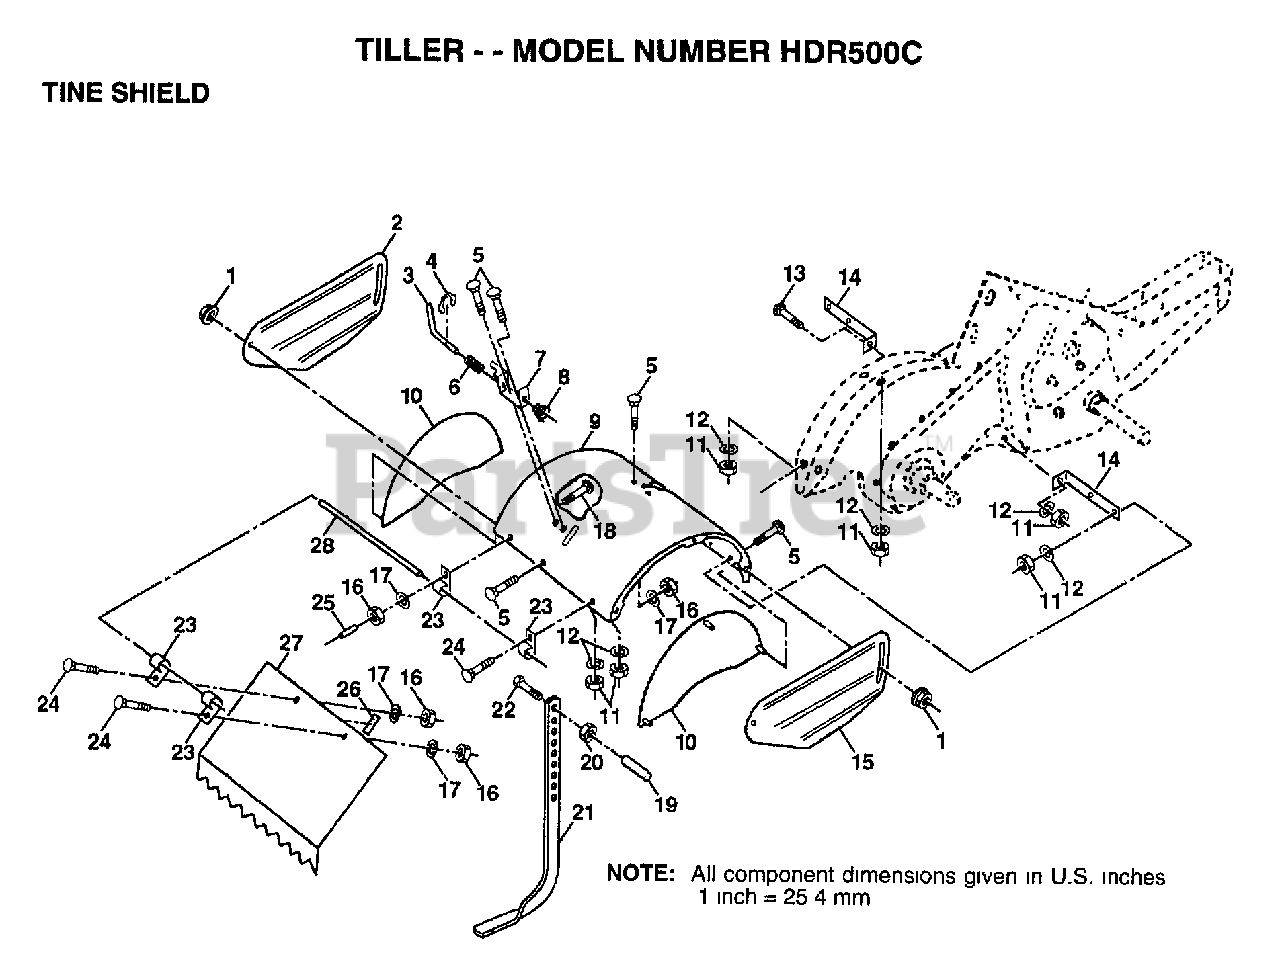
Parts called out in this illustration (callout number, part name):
1	NUT
2	SHIELD.OUT.SD.LH.
3	STAKE PIN TI
4	KLIP RING TI
5	BOLT
6	SPRING TI
7	LATCH BRACKET TI
8	SPRING CRT
9	SHIELD.TINE.PNT.
10	SHIELD.SD.INNER
11	NUT.HEX.5/16-18
12	LOCKWASHER
13	BOLT
14	BRKT SHIELD TINE
15	SHIELD.OUT.SD.RH.
17	LOCKWASHER
18	BOLT
19	GRIP CRT
20	NUT.HEX.3/8-16UNC
22	BOLT
23	HINGE CRT
24	BOLT
25	VINYL CAP TI
26	PAD IDLER TI
27	SHIELD.LEVELING
28	PIN HINGE
